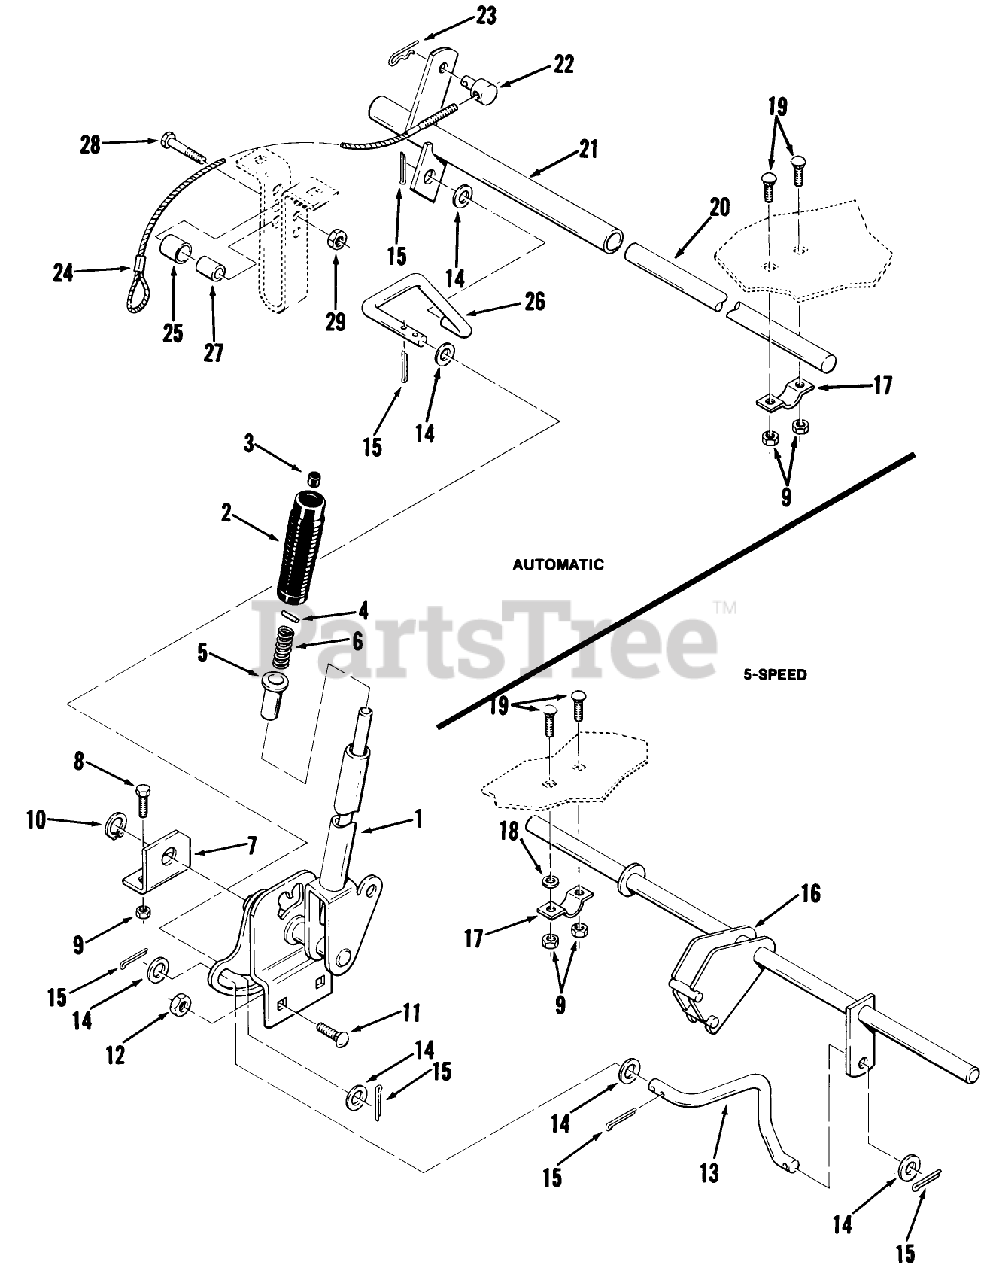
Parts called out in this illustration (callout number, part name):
2	HANDGRIP
3	CAP-ROD, PLUNGER
4	PIN-SPIROL
5	RETAINER-SPRING
6	SPRING-COMPRESSION
17	CLAMP
19	CARRIAGE BOLT -4
20	Lift Shaft
22	TRUNNION-CLUTCH ROD
23	Hairpin Cotter
24	CABLE ASSY
